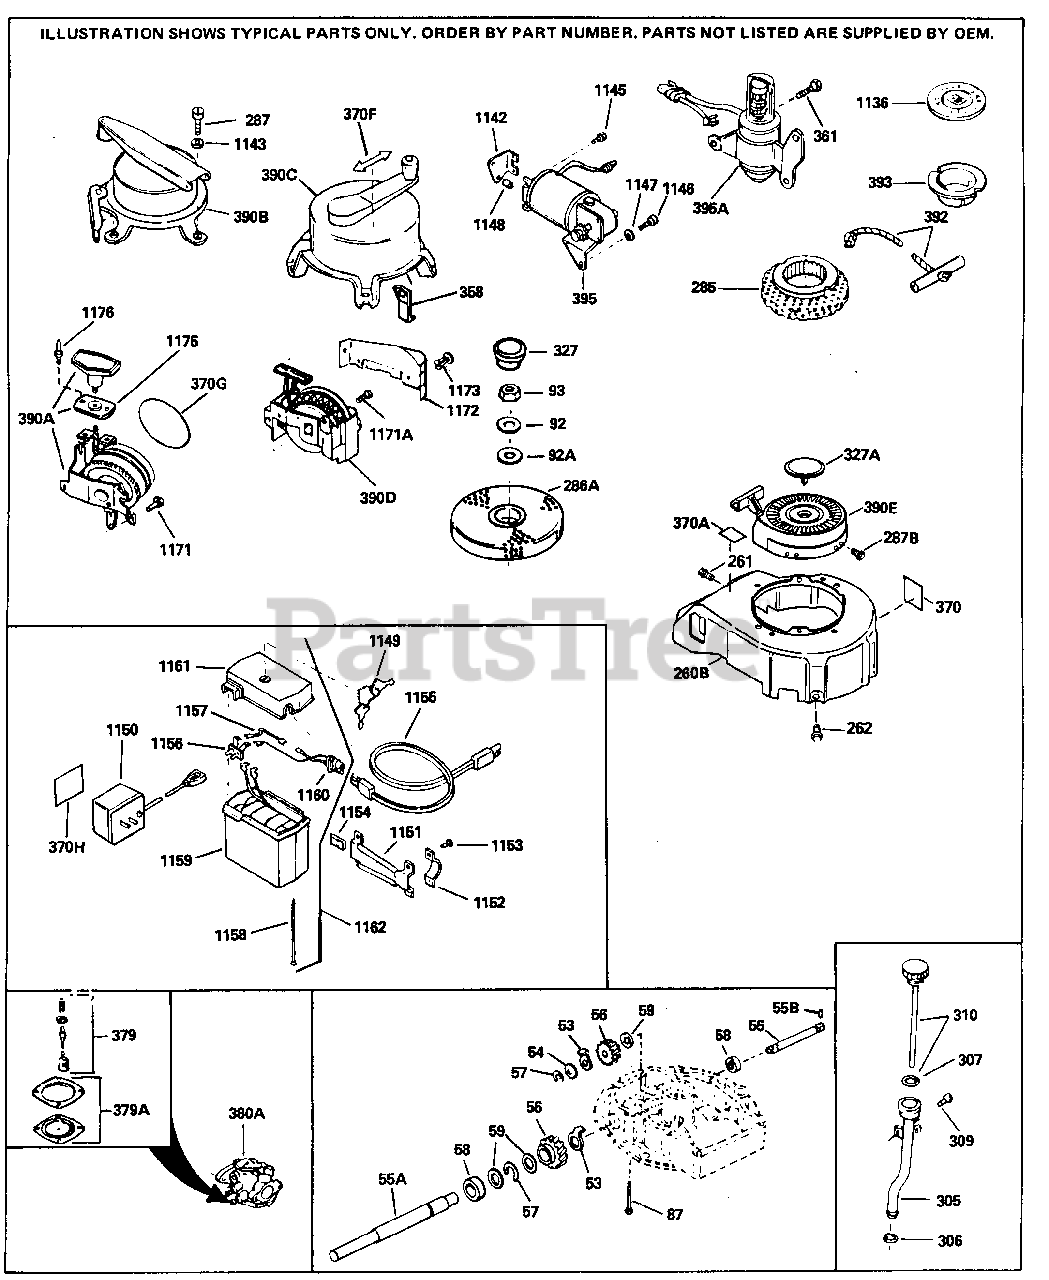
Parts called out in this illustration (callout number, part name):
19	Spring, Governor
92	Washer, Belleville
93	Nut, Flywheel
182	Screw, 1/4-28 x 7/8"
261	Screw, 1/4 20 x 5/8"
262	Screw, 1/4-20 x 5/8"
286A	Screen, Flywheel
287	Pop Rivet (Purchase locally) 3/16" di a.
287	Screw, 1/4-28 x 7/16" Use as require d
287	Screw & Lockwasher, 1/4-28 x 1/2"
305	Oil Fill Tube
306	"O" Ring
306	"O" Ring This "O" ring is required wi th metal fill tube only when replacem ent mounting flange with .777 dia. oi l fill hole has been used.
307	"O" Ring
309	Screw, 10-32 x 1/2"
310	Dipstick (Incl. 307)
370	Decal, Instruction
379	Inlet Needle, Seat, Gasket & Spring A ssy.
379A	Diaphragm Assy. (Incl. gasket)
380A	Carburetor (Incl. 184) (Refer to Divi sion 5, Section A, page 72 or Fiche 6 , Grid D-9 for breakdown)
390A	Side Mount Rewind Starter NOTE: Repla cement hardware may differ when servi cing starter assy. or blower housing. Refer to Service Bulletin 508. (Refe r to Division 5, Section C, page 27 o r Fiche 6, Grid G-4 for breakdown)
1171	Screw, 1/4-20 x 1/2"
1175	Bracket Ass'y. (Use as required)
1176	Open End Rivet (Use as required)
